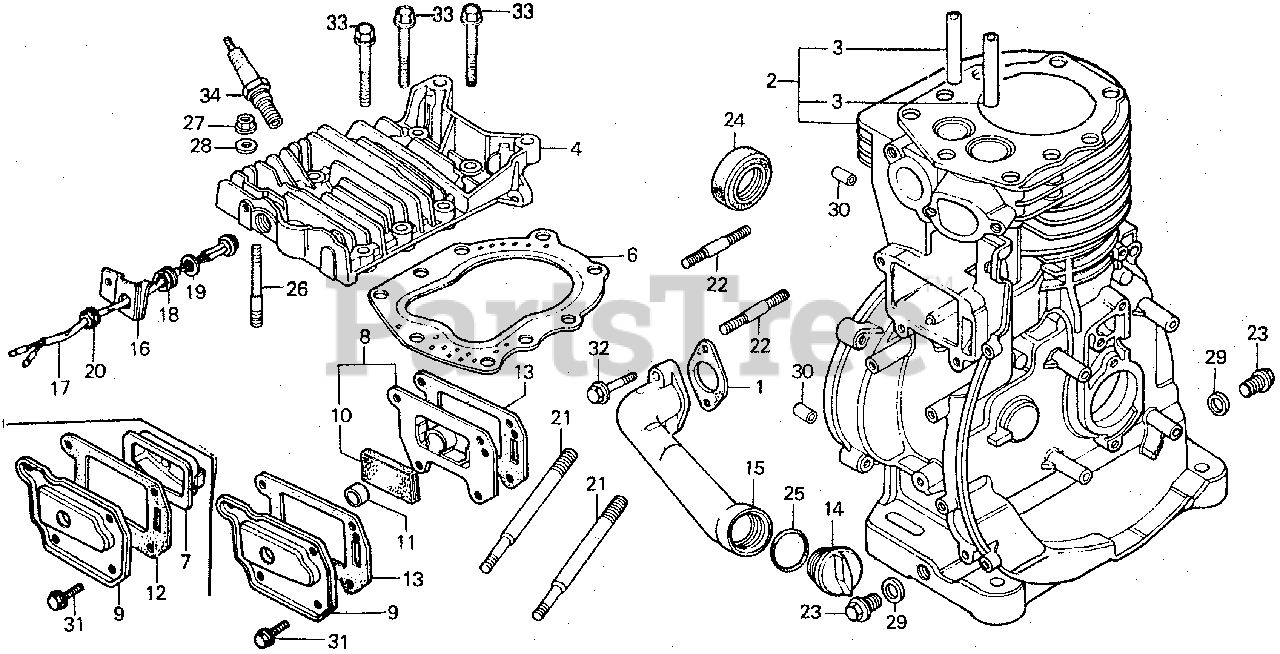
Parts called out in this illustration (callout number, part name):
1	GASKET, OIL PAN
2	CYLINDER (CRANKSHAFT P.T.O.)
2	CYLINDER (CRANKSHAFT P.T.O.) (NOT AVAILABLE)
3	GUIDE, VALVE
4	CYLINDER HEAD (NOT AVAILABLE)
6	GASKET, CYLINDER HEAD
7	CASE, BREATHER
9	COVER, TAPPET
12	GASKET, TAPPET COVER
21	BOLT, STUD (8X110)
21	BOLT, STUD (8X104)
22	BOLT, STUD (8X35)
23	BOLT, DRAIN PLUG
24	OIL SEAL (30X46X8)
25	O-RING (26X2.7)
29	WASHER, DRAIN PLUG (12MM)
30	PIN A, DOWEL (8X14)
31	BOLT, FLANGE (6X12)
32	BOLT, FLANGE (6X25)
33	BOLT, FLANGE (10X55)
34	SPARK PLUG (BR-4HS) (NGK)
